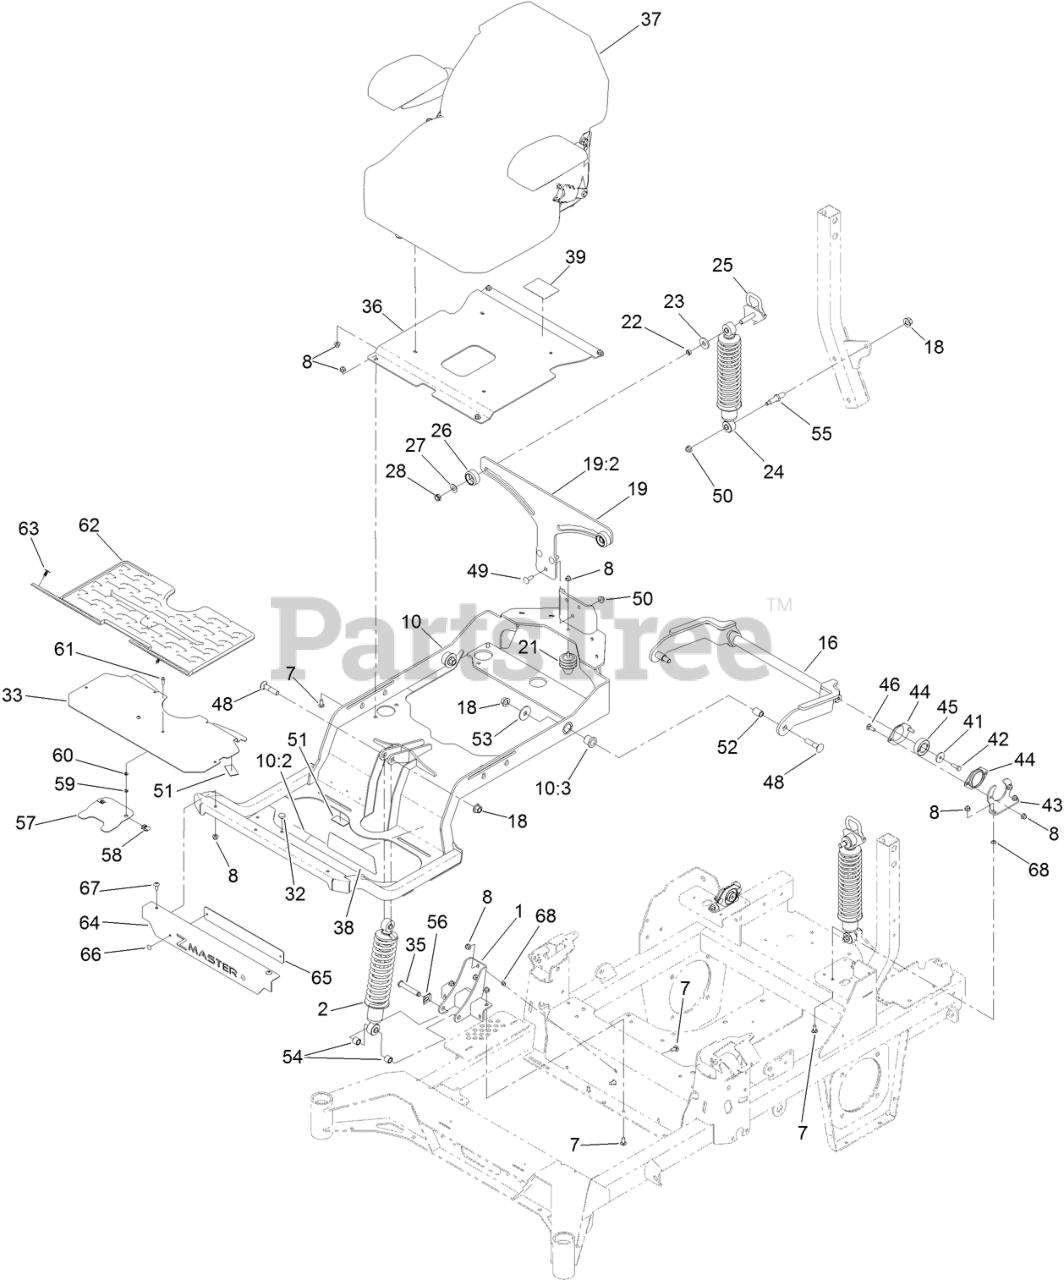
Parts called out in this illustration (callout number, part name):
1	MOUNT-SHOCK, LOWER [BLACK]
2	SHOCK ASM-FRONT
7	SCREW-CARR
8	NUT-HF, NI
10	SUBFRAME ASM
10:2	DECAL-DANGER
10:3	BUSHING-FLANGE
16	ARM-TRAILING
18	NUT-LOCK
19	BRACKET-MOUNTING
19:2	DECAL-ADJUSTMENT, RIDE
21	ISOLATOR
22	BEARING-SLEEVE
23	WASHER-PLASTIC
24	SHOCK/SPRING ASM
25	CAM LOCK ASM
26	KNOB-LOCK, CAM
27	WASHER-ADJUSTING
28	NUT-HEX
32	BUMPER
33	FLOORPAN
35	PIN-CLEVIS
36	PAN-SEAT
37	SEAT ASM-STANDARD
38	DECAL-MYRIDE
39	DECAL-SERVICE AID
41	WASHER-FLAT
42	SCREW-HH, THREAD LOCKING
43	BRACKET-BEARING
44	HOUSING-BEARING, FLANGE
45	BEARING
46	BOLT-CARR
48	SCREW-CARR
49	SCREW-CARR
50	NUT-HF, NI
51	PAD-RUBBER
52	SPACER-ALUMINUM
53	WASHER-THRUST
54	SPACER-TUBE
55	BOLT-SHOULDER
56	CLIP-PIN
57	ADAPTER-CAPTIVE
59	PUSHNUT-RETAINER, BOLT
60	WASHER-FLAT
61	SCREW-HSBH
62	FLOORMAT-MYRIDE
63	PLUG-PLASTIC
64	PLATE-BADGE
65	PLATE-BACKER
66	RIVET-POP
67	SCREW-TORX
68	NUT-PUSH
